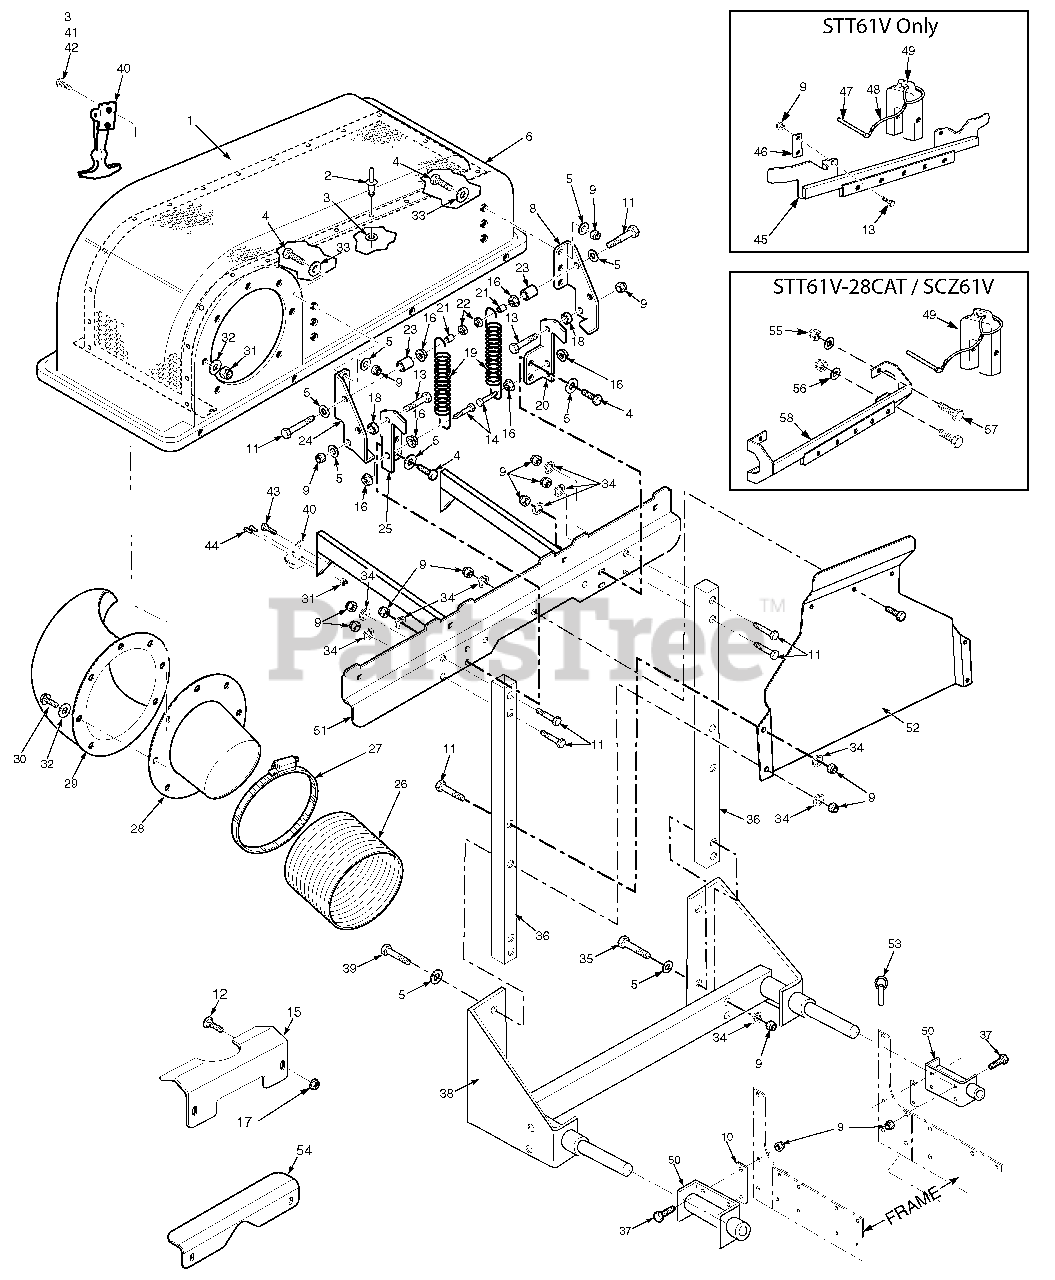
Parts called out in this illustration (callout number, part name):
1	Screen, Catcher Hood
2	Pop Rivet, 3/16 x .652
3	Flatwasher, 3/16-.196 x .469 x .048
4	Bolt, Hex Head 3/8-16 x 1-1/4"
5	Flatwasher, 3/8-.391 x .938 x .105
6	Hood Assembly, GC-STT
7	Bolt, Hex Head 3/8-16 x 2-3/4"
8	Hinge, Upper LH
9	Nut, Elastic Stop 3/8-16
10	Spacer, Hitch
11	Bolt, Hex Head 3/8-16 x 2-1/4"
12	Bolt, Carriage 5/16-18 x 1.00"
13	Bolt, Hex Head 3/8-16 x 1-1/2"
14	Bolt, Hex Head 3/8-16 x 1-3/4" Grade 8
15	Support Bracket, Catcher
16	Nut, Serrated Flange 3/8-16
17	Nut, Hex Serrated Flange 5/16-18
18	Bushing, Hopper Pivot
19	Spring, Hood Hinge
20	Hinge, Lower LH
21	Spacer
22	Locknut, 3/8-16
23	Spacer
24	Hinge, Upper RH
25	Hinge, Lower RH
26	Hose, 8" Dia. x 68"
27	Clamp, 8-5/8" Max Dia.
28	Tube, Filler GC-STT
29	Elbow, GC-STT
30	Bolt, Hex Head 5/16-18 x 1-1/4"
31	Nut, Elastic Stop 5/16-18
32	Flatwasher, 5/16-.375 x .875 x .083
33	Flatwasher, 3/8- .406 x 1-1/2" x .179
34	Lockwasher, 3/8 Spring
35	Bolt, Hex Head 3/8-16 x 3-3/4"
36	Tube, Upright
37	Bolt, Hex Head 3/8-16 x 1"
38	Frame Weldment
39	Bolt, Hex Head 3/8-16 x 2-1/2"
40	Latch
41	Screw, #10-32 x 3/4"
42	Nut, Elastic Stop #10-32
43	Bolt, Hex Head 5/16-18 x 3/4"
44	Rivet, 3/16 x .402 POP
45	Support Weldment, Front Weights
46	Clamp, Bar
47	Pin, 1/2 x 6-1/4"
48	Lanyard, Weight Pin
49	Weight Assembly
50	Hitch Bracket Weldment
51	Support Weldment, Bag Frame
52	Heat Shield
53	Quick Pin
54	Support Bracket, GC
55	Nut, Elastic Stop 7/16-14
56	Flatwasher, 7/16-.500 x 1.250 x .083
57	Bolt, Hex Head 7/16-14 x 1-3/4"
58	Support Weldment, Front Weights
